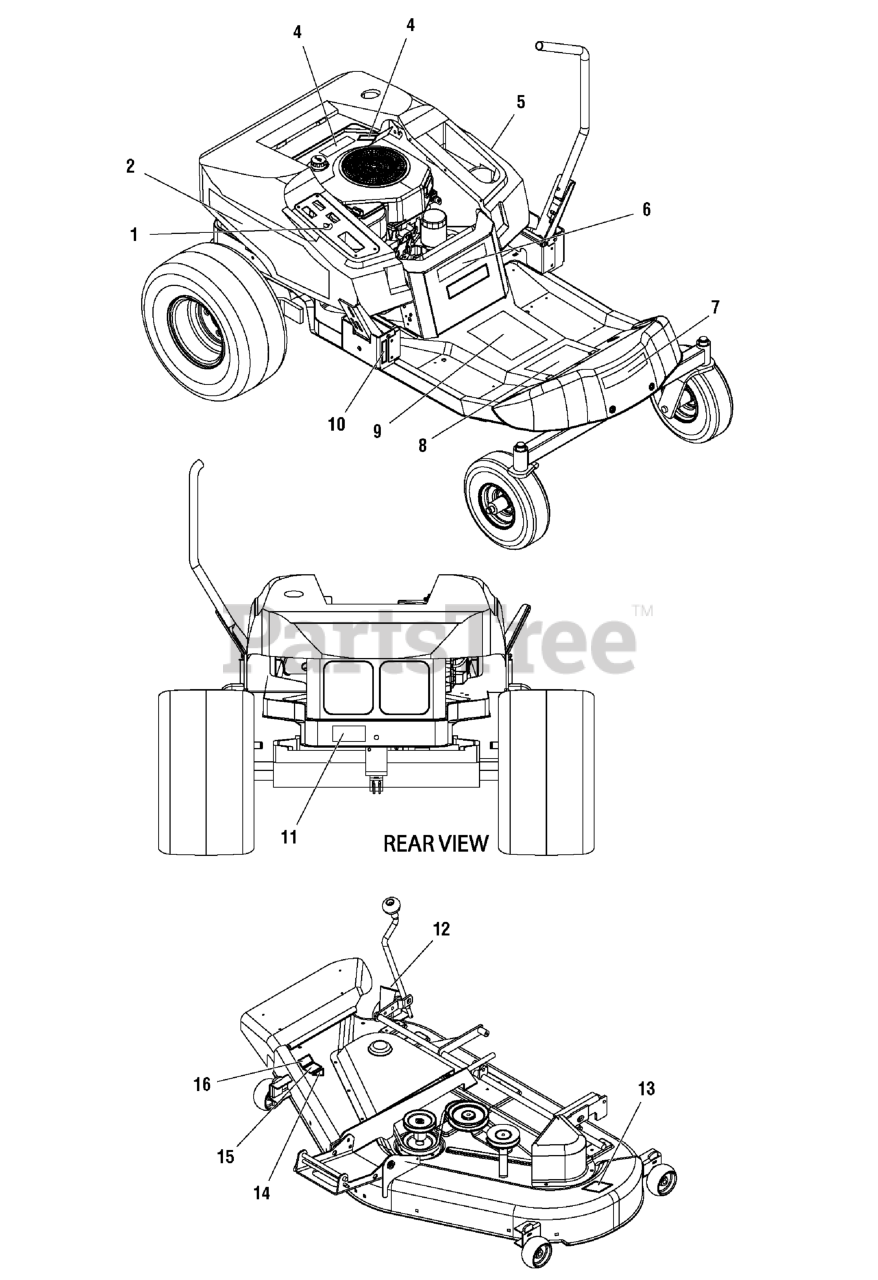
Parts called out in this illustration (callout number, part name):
1	DECAL, Ignition Switch
2	DECAL, Seat Deck Stripe, R.H.
3	DECAL, Engine 18HP Kohler
4	DECAL, Do Not Remove Foam Seal
5	DECAL, Seat Deck Stripe, L.H.
6	DECAL, ZT 7000 (2044)
6	DECAL, ZT 7000 (2250)
7	DECAL, CRAFTSMAN
8	DECAL, Panel Upper, Operation
9	DECAL, Panel Lower, Warning/Danger & Icon Indicator
10	DECAL, Tracking
11	DECAL, Transmission Release Valve
12	DECAL, Height of Cut
13	DECAL, Danger (Do Not Put Hands/Feet in Mower)
14	DECAL, OPEI Certified (Not Serviced)
15	DECAL, 44" Mower Deck
15	DECAL, 50" Mower Deck
16	DECAL, Danger (Do Not Operate With Out Deflector)
